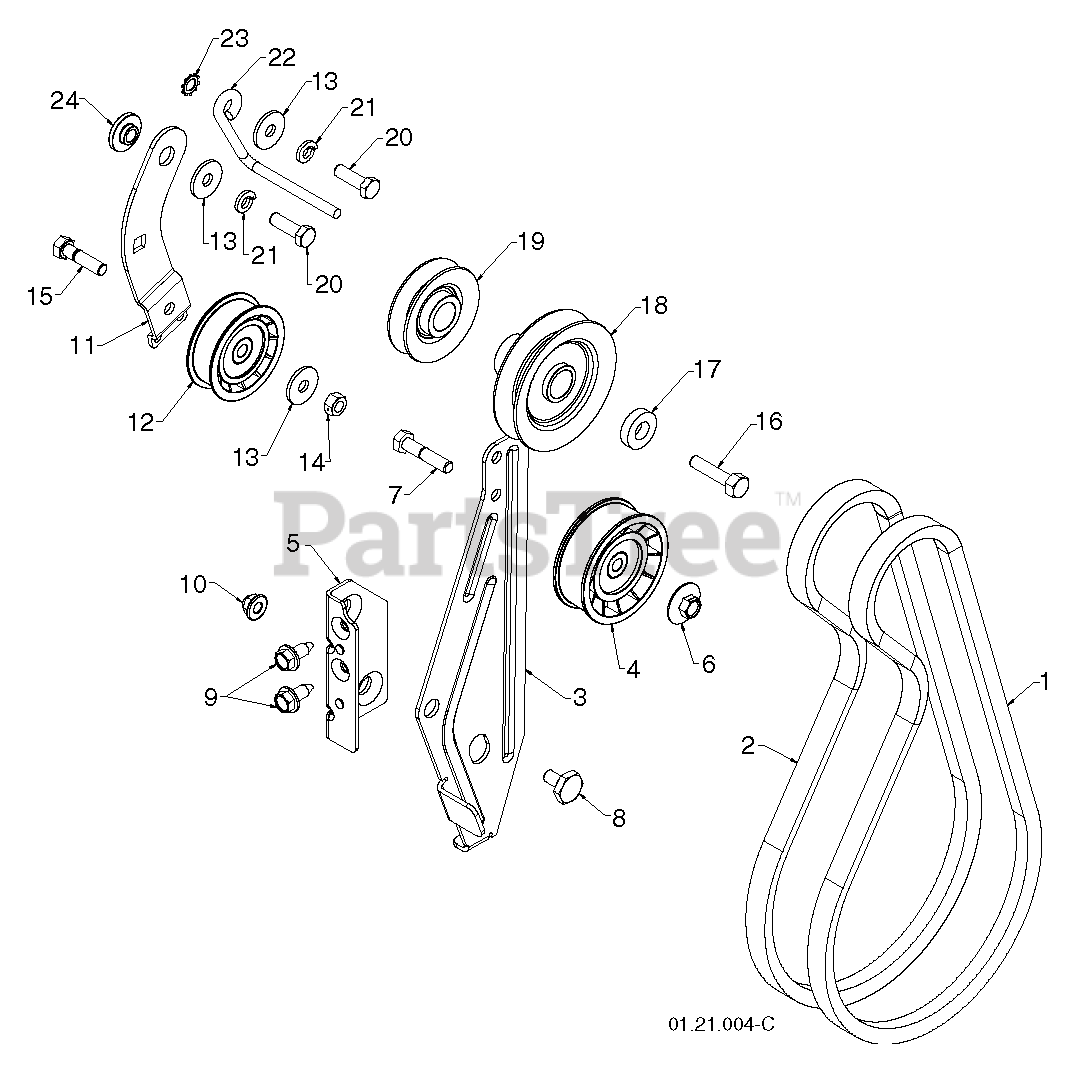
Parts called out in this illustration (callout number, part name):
1	BELT-V.IMPELLER.HS
2	V-BELT.TRACTION
3	RP ARM.IDLER.BRAKE.
4	PULLEY.IDLER.W/SPACER.
5	RP BRACKET.IDLER.PIVOT
6	NUT.FLANGE.HEX.5/16X18.BLACK
7	HEX BOLT
8	BOLT.SHOULDER.1/2X12
9	BOLT.5/16HEX.WHS.HD
10	NUT, LOCK 5/16-18
11	ARM, IDLER
12	PULLEY.W/SPACER.2.25
13	STEEL WASHER
14	NUT.71038.31-18.HEX.NYLOCK
15	BOLT.5/16-18X1-1/4 FULL.THREAD
16	SCREW, HEX HD 3/8-24 X 1-3/8
17	WASHER, FLAT 3/8
18	PULLEY.ENG.IMPELLER.
19	PULLEY.ENG.TRACTION
21	LOCKWASHER
22	GUIDE BELT
23	WASHER EXT TOOTH LOCK 5/16
24	BUSHING, IDLER PIVOT
